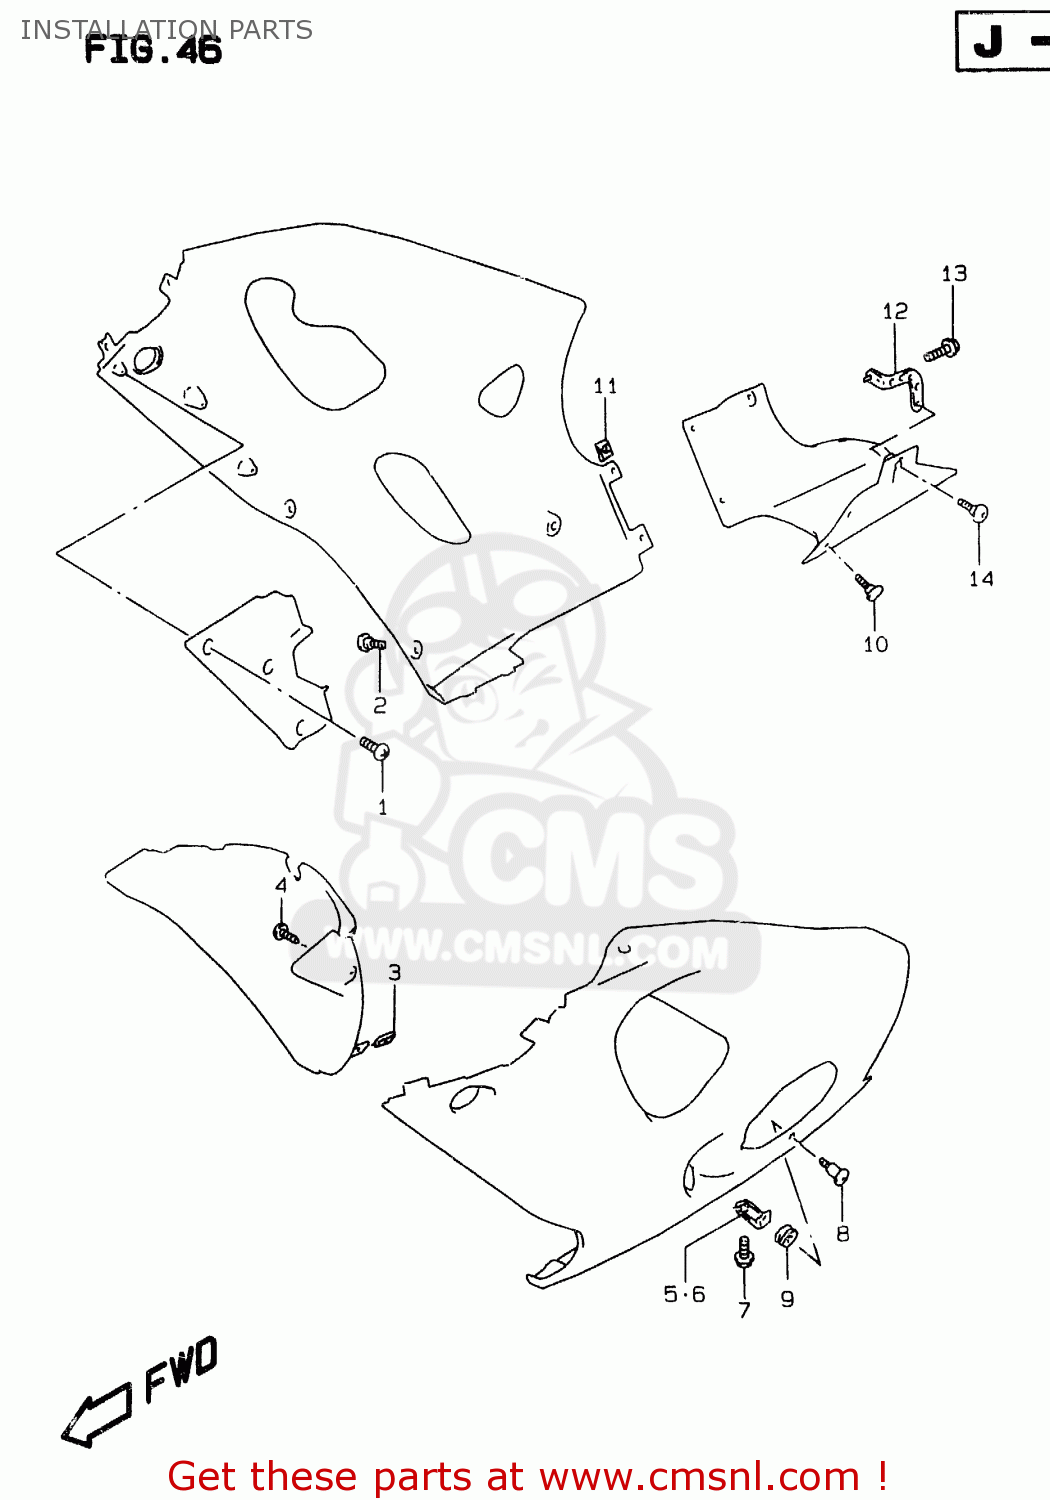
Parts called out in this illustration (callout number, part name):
1	SCREW
2	SCREW(5X16)
3	NUT,HEADLAMP HOUSING,UPPER
4	SCREW
5	BRACKET,UNDER COWLING,LOWER
6	BRACKET,UNDER COWLING,LOWER
7	BOLT
8	SCREW(6X20)
9	CUSHION
10	SCREW(5X16)
11	NUT,HEADLAMP HOUSING,UPPER
12	BRACKET,RR UNDER COWLING
13	BOLT
14	SCREW(5X16)
